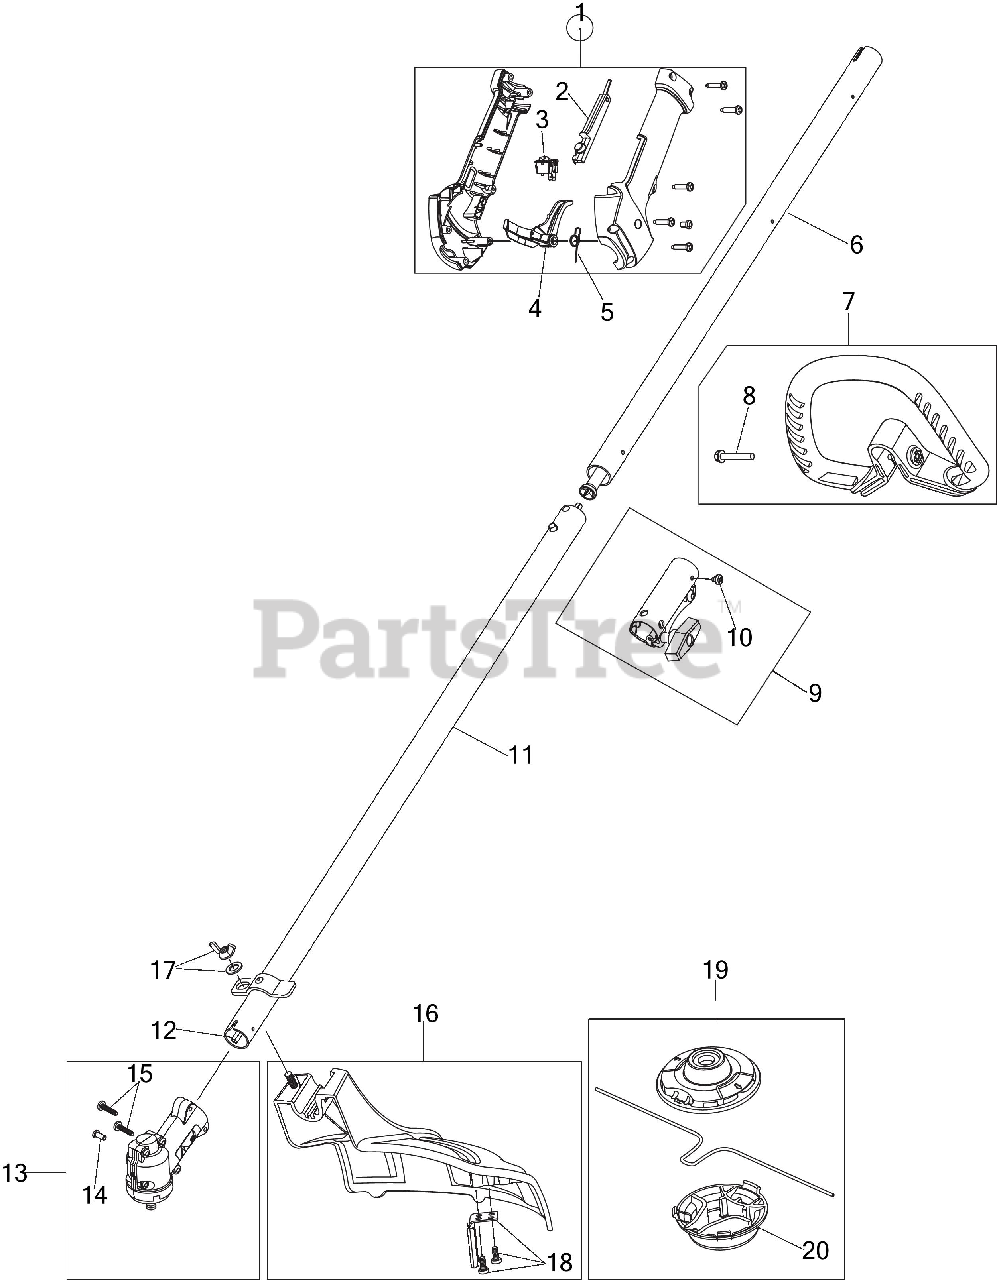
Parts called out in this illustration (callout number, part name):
1	THROTTLE GRIP ASSEMBLY
2	LOCK OUT LEVER
3	SW, MOMENTARY ON/O
4	THROTTLE TRIGGER
5	SPRING TRIG
6	BOOM ASSEMBLY UPR
7	HANDLE ASSEMBLY
8	BOLT 1/4-20X1 1/2
9	E-Z LINK COUPLER
10	SCREW, 10-32X.250 TA
11	BOOM ASSEMBLY LOWER
12	LOWERIBLE DRIVE SHAFT
13	GEARBOX LCBC
14	SCREW, 8-32 x .312 P
16	GUARD ASSEMBLY
17	BLADE GUARD MOUNTING HARDWARE
18	BLADE ASSEMBLY W/HDW
19	HEAD ASSEMBLY FIXED LIN
20	HEAD FIXED LINE BT
